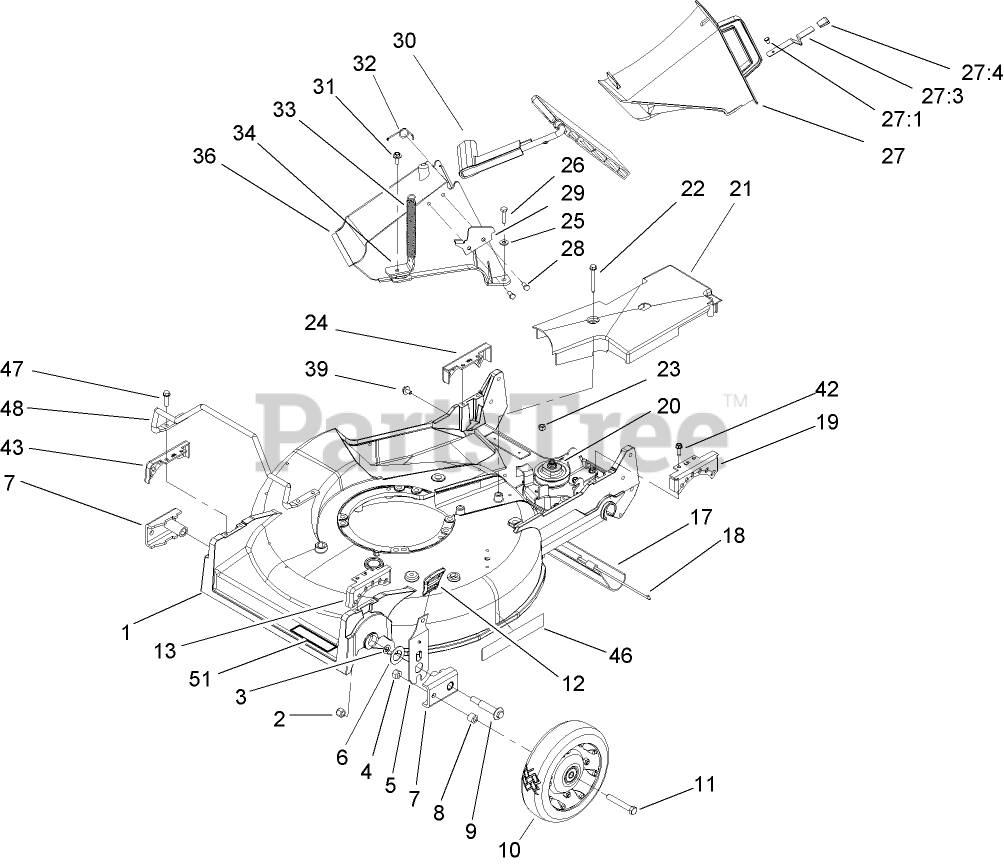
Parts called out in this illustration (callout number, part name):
1	HOUSING ASM
2	NUT-LOCK
3	WASHER
4	NUT-LOCK, CONE
6	WASHER-THRUST
7	ARM-PIVOT, FRONT
8	SPACER-WHEEL
11	SCREW-HH
12	KNOB-HOC
13	QUADRANT-FRONT, LH
18	ROD-SHIELD
19	QUADRANT-REAR, LH
21	COVER-BELT
22	SCREW-HWH
23	NUT-LOCK, NI
24	QUADRANT-REAR, RH
25	WASHER-FLAT
26	SCREW-HH
27	DISCHARGE PLUG ASM
27:1	RIVET-HEAD, FLAT
27:3	LATCH-PLUG, DISCHARGE
27:4	GRIP-LATCH
28	SCREW-PLASTITE
29	LATCH-PLATE
30	DISCHARGE DOOR ASM
31	SCREW-HWH
32	RETAINER-DOOR
33	SPRING-DOOR
34	BRACKET-SPRING
36	TUNNEL-DISCHARGE
39	SCREW AND WASHER ASM
42	SCREW-HWHTF
43	QUADRANT-FRONT, RH
47	SCREW-HWHTF
48	GUARD-ENGINE
51	DECAL-BLADE
